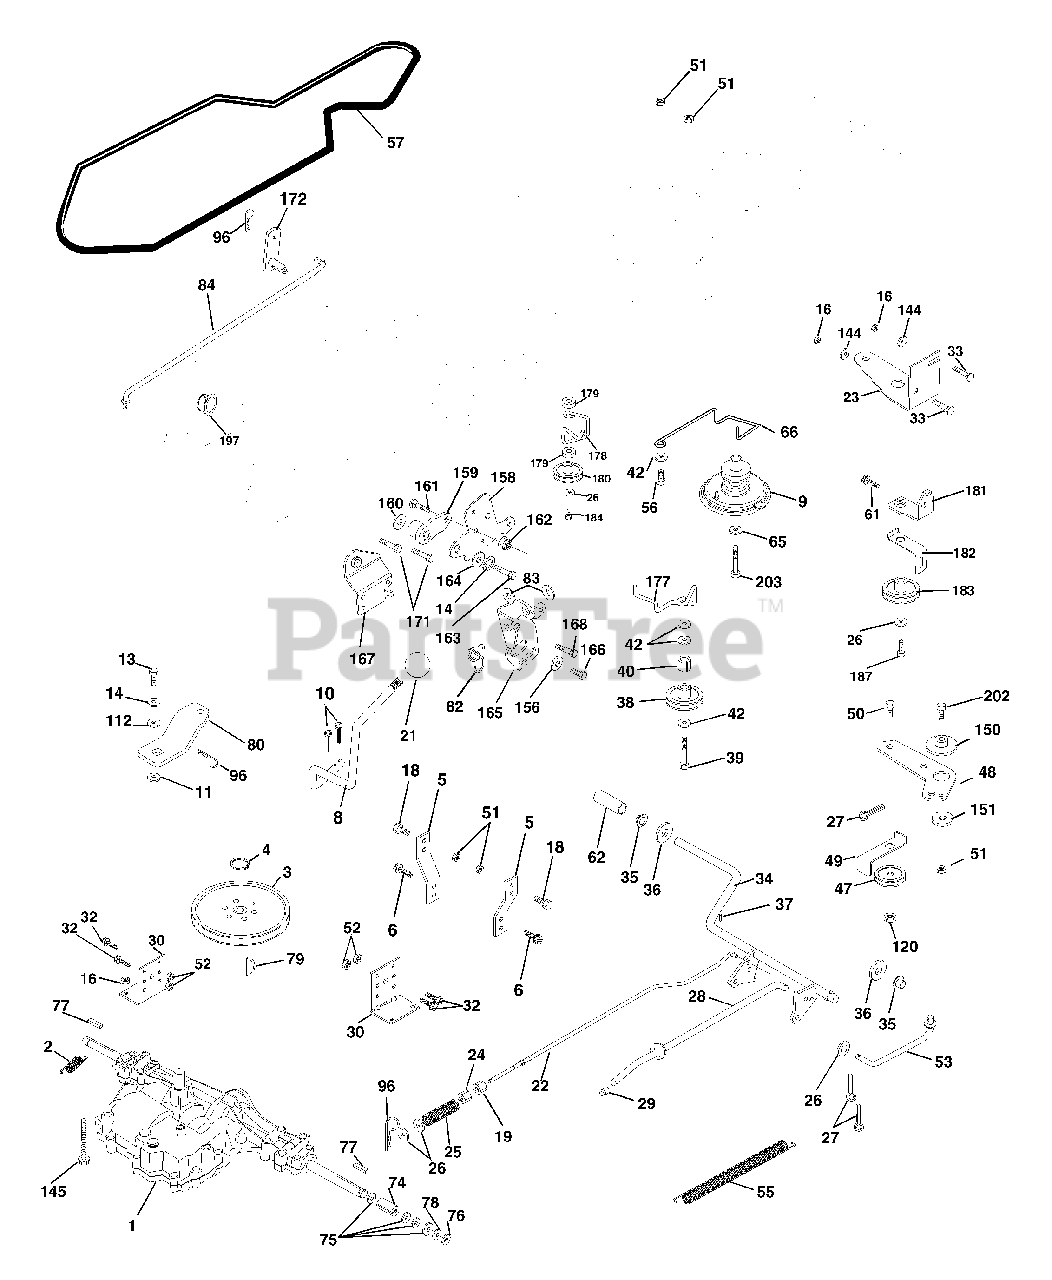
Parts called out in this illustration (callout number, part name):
2	Spring Brake Return
3	Pulley Transaxle
4	Ring Retainer #5100-62
5	Strap torque 30 degrees
8	Rod Shift Fender Adjust Lt
9	Clutch Asm Noram
10	Pin, Cotter 1/8 x 1
11	Washer Plate Shf .3888 sq hole
13	Bolt 1/4-28 Unf Gr 8 w/patch
14	Washer, Lock Hvy Helical
16	Nut, Lock Hex w/Ins 5/16-18 UNC
18	Bolt Hex 3/8-16 UNC x 1 Gr.5
19	Nut, Lock Hex w/Wsh 3/8-16 UNC
21	Knob Duckhead 1/2-13 Unc Blk
22	Rod, Brake CRD 0650
23	Bracket Clutch Noram
24	Nut
25	Spring, Rod, Brake
26	Washer 13/32 x 13/16 x 16 Ga.
27	Pin, Cotter 1/8 x 3/4
28	Rod, Parking Brake
29	Cap, Parking Brake
30	Bracket, Mfg. Transaxle
32	Bolt Hex 5/16-18 UNC x 3/4
33	Bolt Rdhd Sqnk 5/16-18 Unc x 3/4
34	Shaft, Asm Pedal Foot CRD
35	Bearing, Nylon
36	Washer 21/32 x 1 x 16 Ga.
37	Pin, Roll 3/16 x 1"
38	Pulley, Flat
39	Bolt Fin Hex 3/8-16 UNC x 2-3/4
40	Spacer, Split 395 x 59 Bzp
42	Washer 13/32 x 13/16 x 12 Ga.
47	Pulley, Idler, V Groove Plasitc
48	Bellcrank Clutch Grnd Drv
49	Retainer, Belt Style Spring
50	Bolt Hex Hd 3/8-16 UNC x 1-1/2
51	Nut, Crownlock 3/8-16 UNC
52	Nut Crownlock 5/16-18
53	Link, Clutch 7.66
55	Spring, Return, Clutch
56	Bolt, Hex 3/8-16 UNC x 1-1/4
57	V-Belt Kev PMST CRD
61	Screw 3/8-16 x 3/4
62	Cover, Pedal
65	Washer
66	Keeper, Belt Engine F-Proof
74	Spacer Axle
75	Washer 25/32 x 1-1/4 x 16 Ga.
77	Key, Square
78	Washer 25/32 x 1-5/8 x 16 Ga.
79	Key Woodruff
80	Arm Shift PMST 20" Tires
82	Spring, Torsion
83	Washer 17/32 x 3/4 x 16 Ga.
84	Link Shift CRD Pmst 18" Tires
96	Spring, Retainer 1"
112	Washer 9/32 x 3/4 x 10 Ga.
144	Washer 11/32 x 5/8 x 16 Ga.
145	Bolt Hex FGHD 5/16-18 x Gr 5
150	Bushing, Bellcrank Grnd Dr
151	Washer 13/32 x 2 x 10 Ga.
153	Bolt Hex Hd 5/16-18 Unc x 1
156	Washer Srred 5/16 ID x 1.125
158	Bracket Shift Mount
159	Hub Tapered Flange Shift Lt
160	Washer 29/32 x 1-1/4 x 16 Ga.
161	Bolt Rdhd Sqnk 1/4-20 x 3/4 Gr 5
162	Nut Crownlock 1/4-20 Unc
163	Bolt Hex Fin 1/4-20 Unc x 1 Gr 5
164	Washer 5/8 x .281 x 10 Ga.
165	Bracket Pivot Lever
166	Screw 5/16-18 x 5/8
167	Bracket Support Shift CRD
168	Bolt Shoulder 5/16-18 x .561
171	Screw Thdrol 3/8-16 x 1/2 Ty-Tt
172	Shaft Asm Shift Front CRD PMST
177	Keeper Flat Idler 3.06" CRD
178	Keeper Belt Idler 1.88" CRD
179	Washer Sintered
180	Pulley Flat Composite 3.06"
181	Bracket Idler Ground Drive CRD
182	Keeper Belt 2.5" Od V-Idler CRD
183	Pulley V-Idler 2.50" Od CRD
184	Screw Hexwsh Thdrol 3/8-16 x 2-3/4
187	Screw Thdrol 3/8-16 x 1-1/4
202	Bolt Carr Sh 3/8-16 x 1/2 Ty-Tt
203	Bolt Hex 7/16-20 x 5
